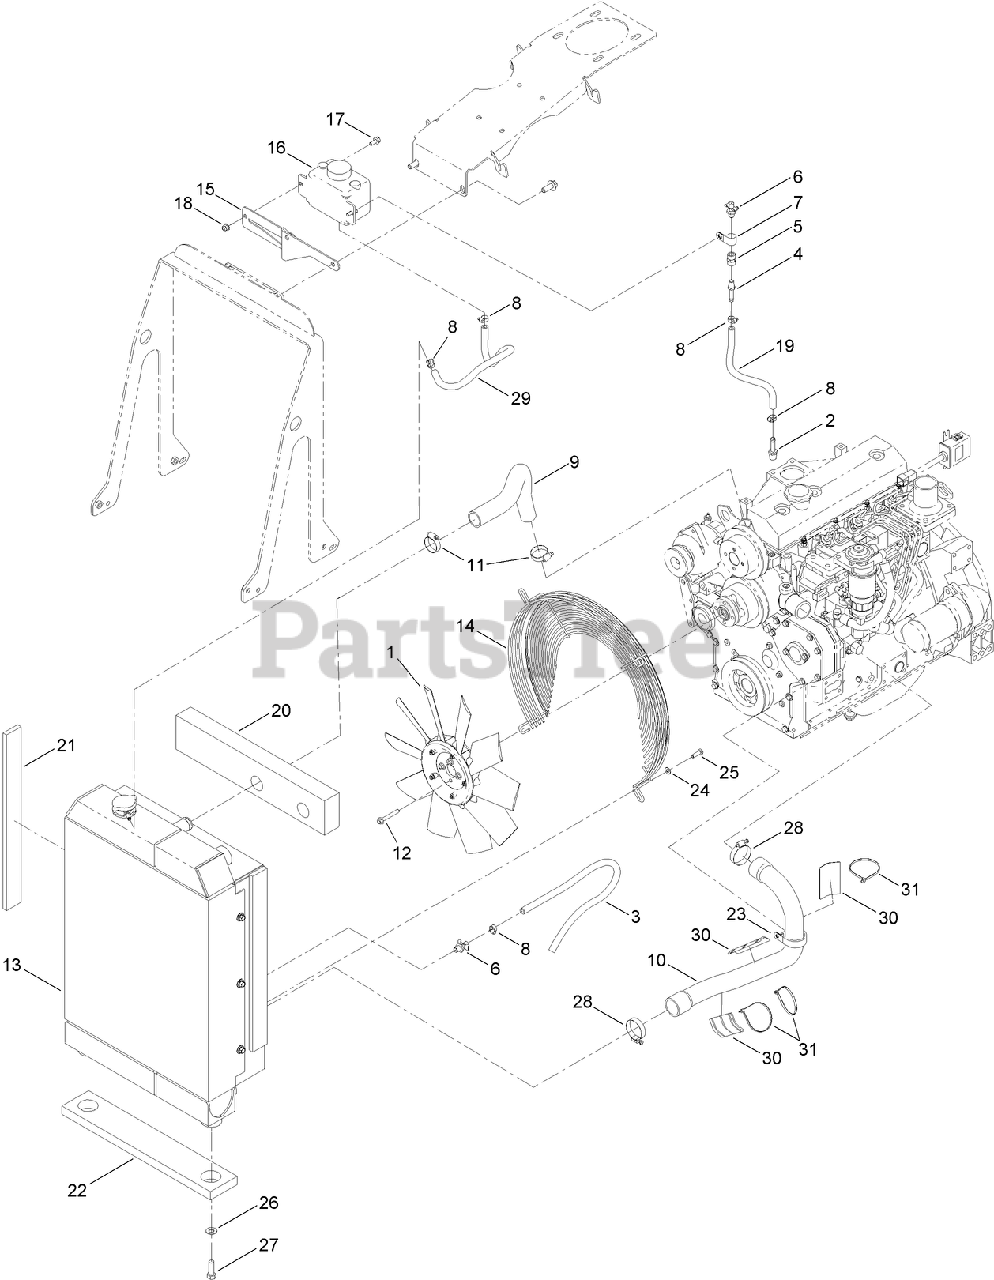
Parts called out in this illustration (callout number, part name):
1	FAN-COOLING
2	STEM-STRAIGHT, BEAD
3	HOSE-FUEL
4	STEM-STRAIGHT, BEAD
5	COUPLING-PIPE (NPTF)
6	VALVE-SHUTOFF
7	CLAMP-R
8	R-CLAMP
9	HOSE-RADIATOR, UPPER
10	HOSE-RADIATOR, LOWER (MOLDED)
11	CLAMP-HOSE
12	SCREW-FLANGE
13	COOLING ASM
14	GUARD-Fan
15	MOUNT-TANK, OVERFLOW
16	TANK-Overflow
17	SCREW-HHF
18	NUT-TORQUE, PREVAILING
19	HOSE-FUEL
20	SEAL-FOAM
21	SEAL-FOAM
22	SEAL-FOAM
23	CLAMP-R
24	WASHER-PLAIN
25	SCREW-HH
26	WASHER-FLAT
27	SCREW-HH
28	CLAMP-HOSE
29	HOSE-FUEL
30	PROTECTOR-HOSE
31	TIE-CABLE
